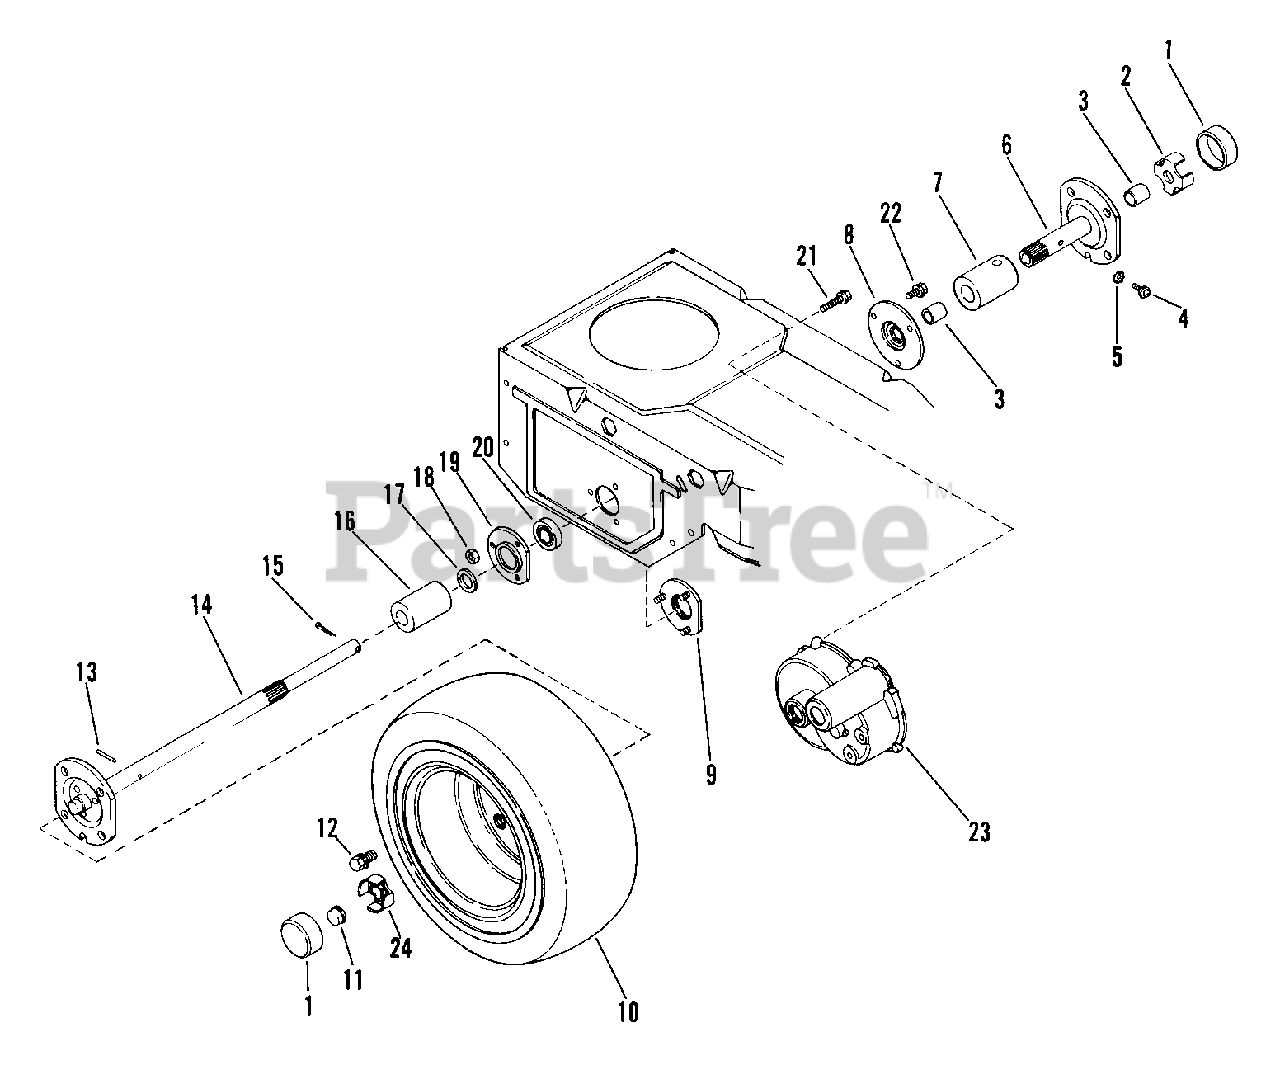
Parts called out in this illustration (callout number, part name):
1	HUB CAP
2	SPINDLE CUP
2	BSHG-SLV .690X.814X1.000 BR
4	SPIN DRIVE ZERK FITTING
5	WSHR-LK .250X.047 LT PL
6	L.H. AXLE ASSEMBLY
7	TUBE
8	SEAL 1.125X2.496X.380
9	BEARING FLANGE
10	T/WHL ASSY 4.80/4.00 X 8
10	TIRE
10	WHL
10	T/WHL ASSY 6.50-8 X 16
10	TIRE 16X6.50-8 2 PLY
10	T/WHL ASSY 16X6.5-8
11	PUSHNUT
12	SCR-TAP .500-20X.62 HH PL
13	PIN-ROLL .188X1.25
14	R H AXLE
14	RH AXLE
15	PIN-COTR .12X1.0 PL
16	TUBE
17	WSHR-FL-STL .880X1.380X.062
18	NUT-LK-FLG .250-20 PL
19	BEARING FLANGE
20	BRG-BALL .876 X 1.750 X .50
21	SCR-TAP .312-18X1.50 HWH PL TR
22	SCR-TAP.250-20X.62 HWH BLK ZC
23	GEAR CASE ASSEMBLY
24	SPINDLE CUP
